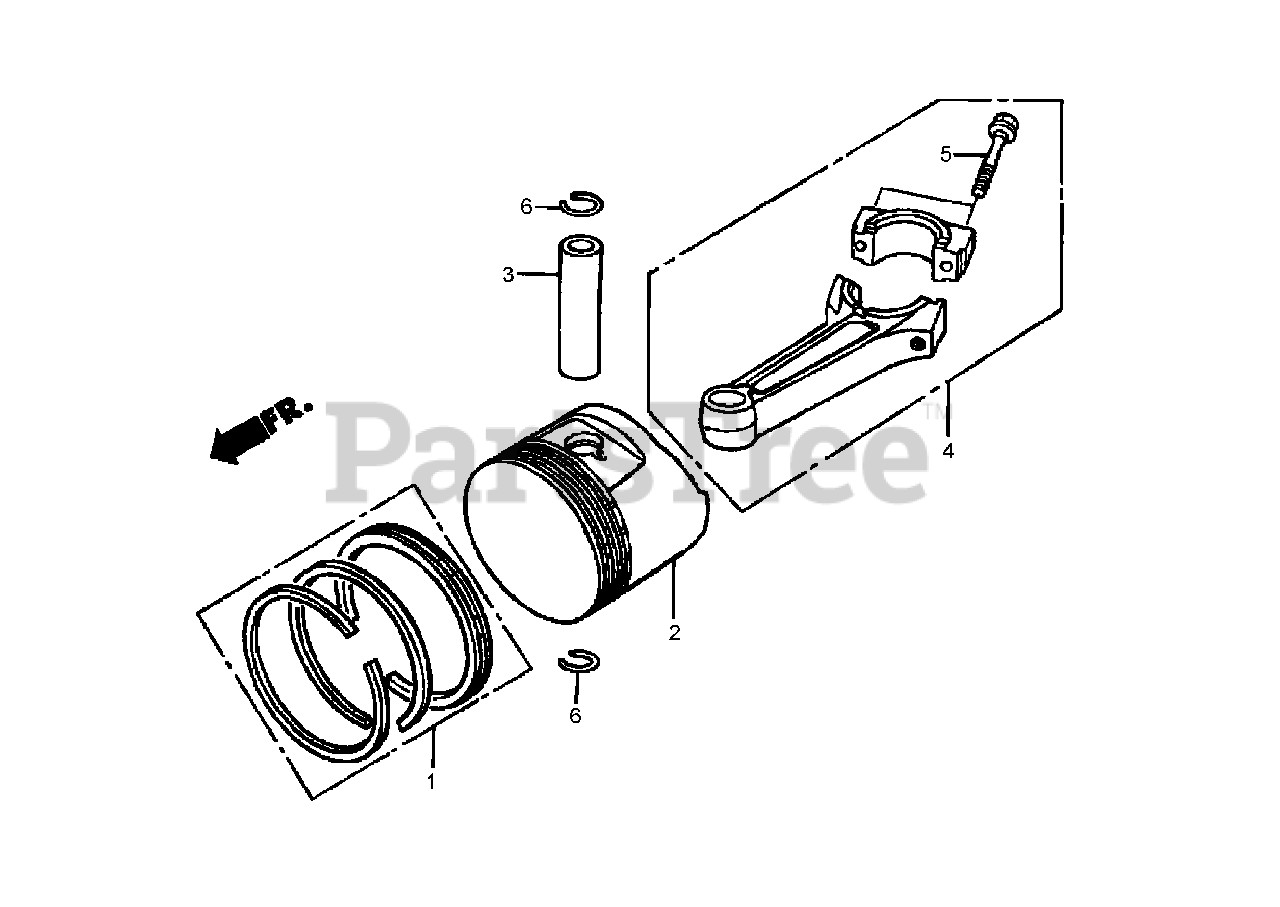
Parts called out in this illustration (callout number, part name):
1	RING SET-PISTON (STD)
1	RING SET-PISTON (OS 0.25)
1	RING SET-PISTON (OS 0.50)
1	RING SET-PISTON (0.75)
2	PISTON (STD)
2	PISTON (OS 0.25)
2	PISTON (OS 0.50)
2	PISTON (0.75)
3	PIN-PISTON
4	CONNECTING ROD ASM
4	CONNECTING ROD ASM (0.25 LOWER SIZE)
5	BOLT-ROD, CONNECTING
6	CLIP-PIN, PISTON (20MM)
